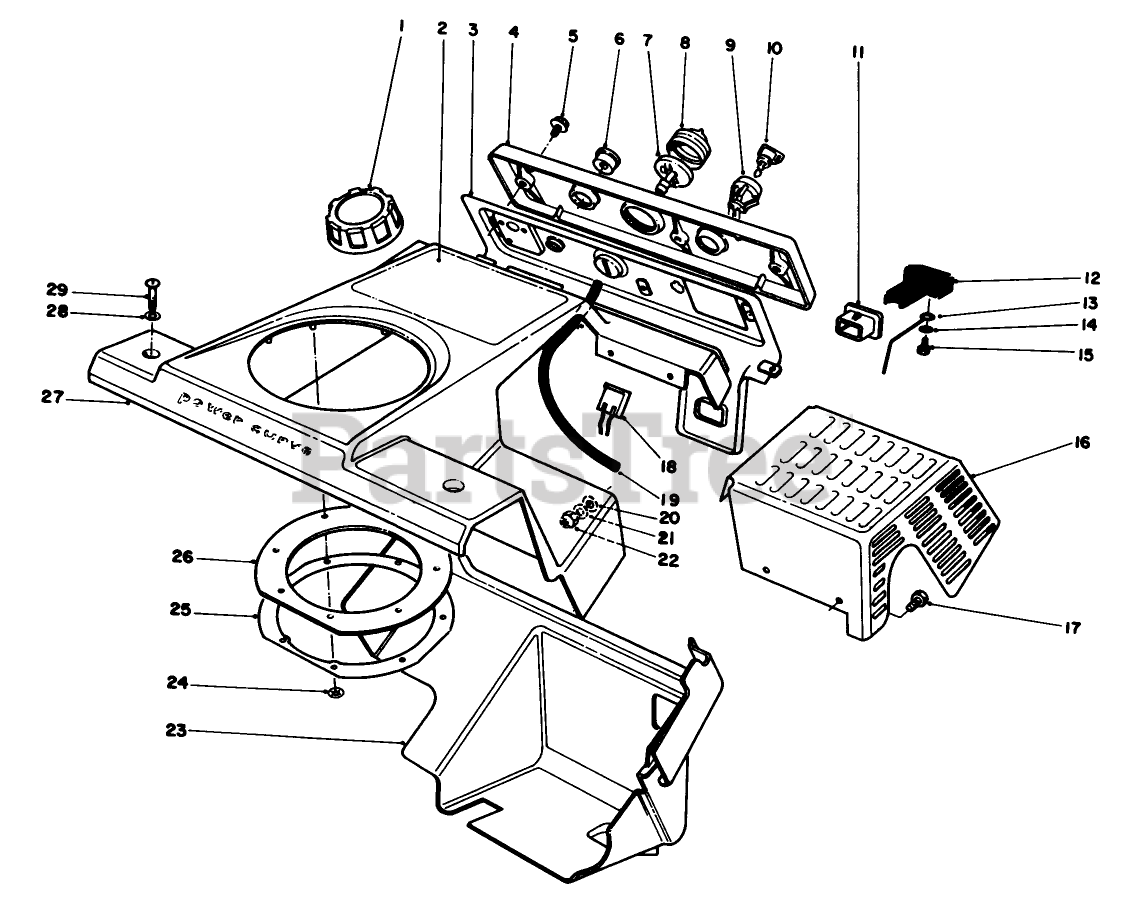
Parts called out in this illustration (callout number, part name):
3	CONT PANEL/PRIMER BODY
5	SCREW
6	GUIDE-ROPE, STARTER
7	BODY-PRIMER
8	BULB-PRIMER
9	SWITCH
10	KEY-IGNITION
11	FITTING
12	CONTROL-CHOKE
15	#8 X .625" PHILPS PAN H
17	SCREW-SHH
18	CONNECTOR-BODY
19	PRIMER HOSE
20	WASHER
21	WASHER-FLAT
22	NUT-LOCK, SIDE
24	PALNUT
28	WASHER-FLAT
29	SCREW-PPH
